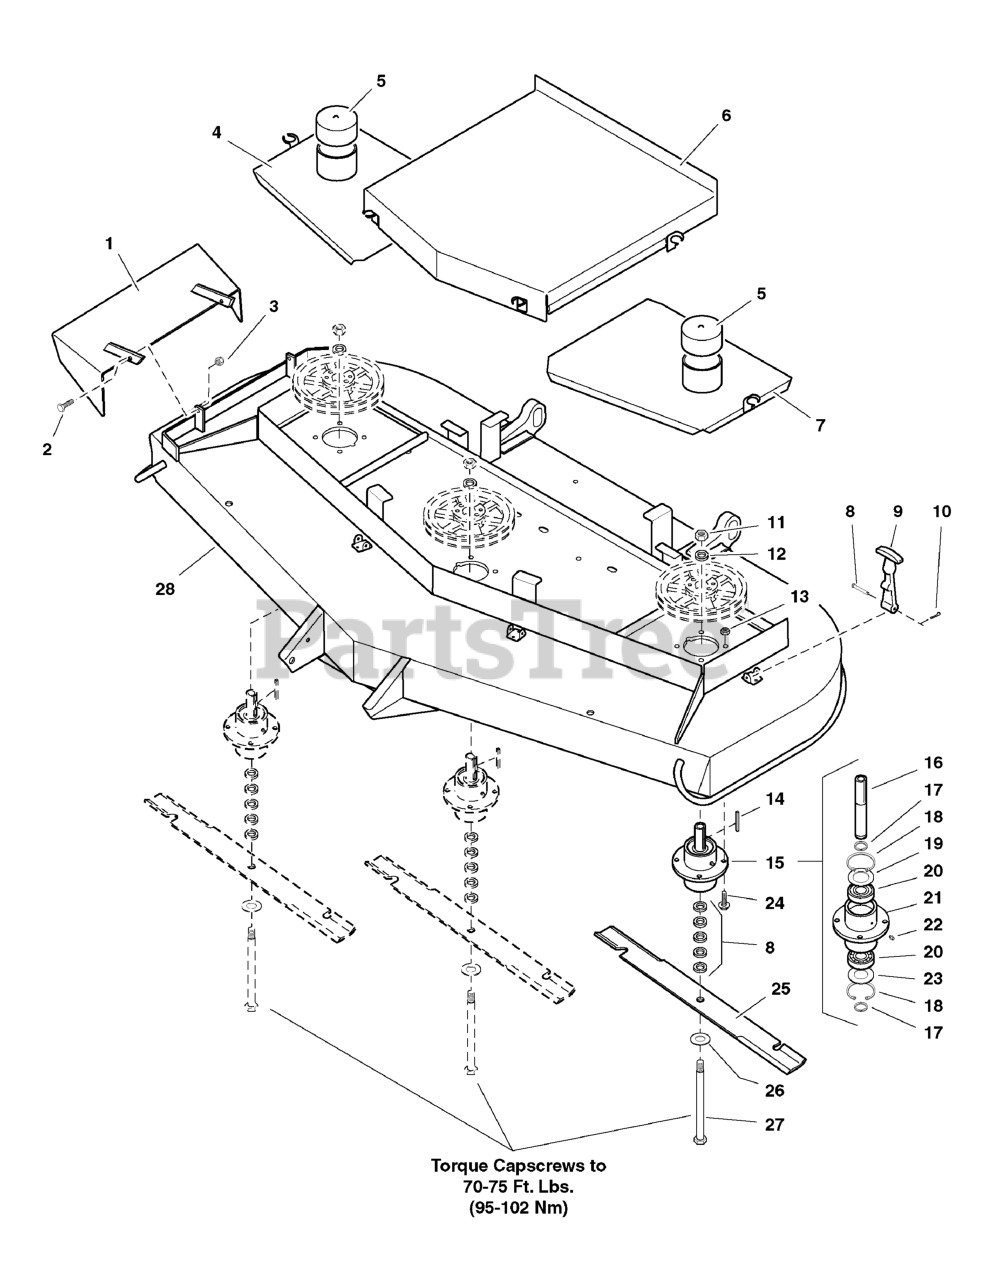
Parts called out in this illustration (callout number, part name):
1	DISCHARGE CHUTE
2	BOLT, 5/16-18 X 1 GD5 YZ
3	NUT, 5/16-18 Hex Nylon Lock
4	WELD, 72" GUARD - RH
5	VINYL CAP
6	CENTER DECK GUARD
7	SPINDLE COVER-LH
8	CLEVIS PIN
9	RUBBER LATCH
10	COTTER PIN
11	NUT, 5/8-11 Hex
12	SPACER, .63 x 1.06 x .23
13	NUT, 5/16-18 Hex Nylon Lock
14	KEY, 1/4 SQ. X 2-1/2
15	SPINDLE ASSEMBLY, Complete
16	SPINDLE SHAFT
17	SNAP RING, External
18	SNAP RING, Internal
19	SPINDLE WASHER, Top
20	BEARING
21	SPINDLE HOUSING
22	GREASE FITTING
23	SPINDLE WASHER, Bottom
24	BOLT, Flange Head, 5/16-18 x 1-1/2
25	MOWER BLADE, 24-1/2"
26	WASHER, 5/8" USS
27	BOLT, 5/8-11 x 9-1/2
28	DECK SHELL W/DECALS, P72, SIDE DISCHARGE
